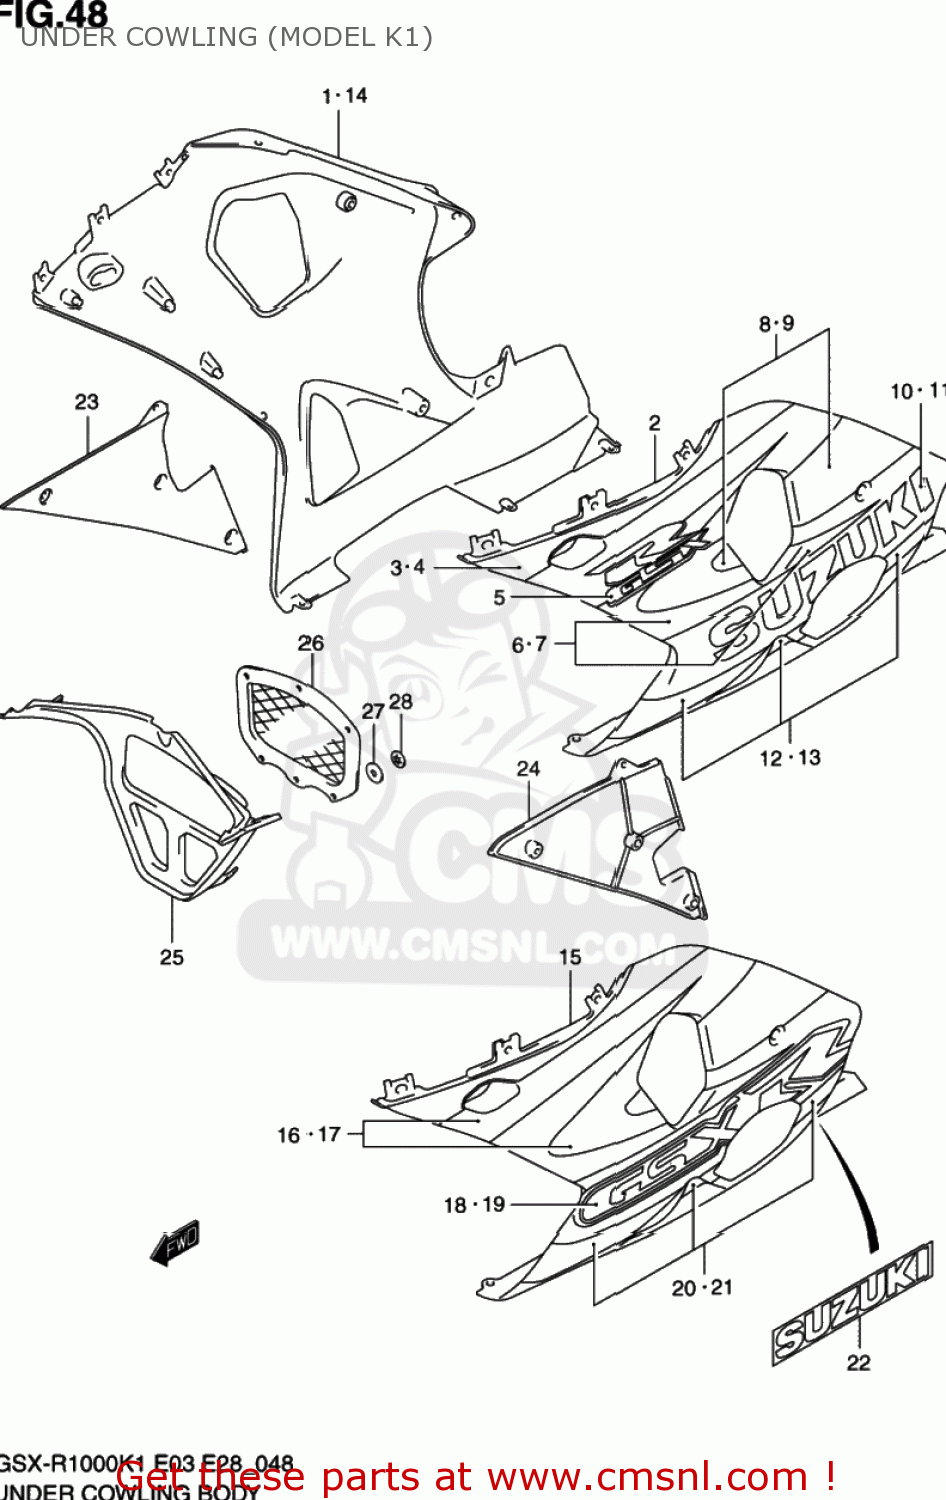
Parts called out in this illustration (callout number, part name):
1	COWLING ASSY,UNDER,R
2	COWLING ASSY,UNDER,L
3	TAPE,COWL UNDER UPR,R
4	TAPE,COWL UNDER UPR,L
5	EMBLEM,COWLING UNDER,GSX
6	TAPE SET,COWL UNDER,R
7	TAPE SET,COWL UNDER,L
8	TAPE,COWL UNDER MIDDLE,R
9	TAPE,COWL UNDER MIDDLE,L
10	EMBLEM,UNDER,SUZUKI,R
11	EMBLEM,UNDER,SUZUKI,L
12	TAPE SET,COWL UNDER LWR,R
13	TAPE SET,COWL UNDER LWR,L
14	COWLING ASSY,UNDER,R
15	COWLING ASSY,UNDER,L
16	TAPE SET,COWL UNDER UPR,R
17	TAPE SET,COWL UNDER UPR,L
18	EMBLEM,COWLING UNDER,GSXR,R
19	EMBLEM,COWLING UNDER,GSXR,L
20	TAPE,COWL UNDER LWR,R
21	TAPE,COWL UNDER LWR,L
22	EMBLEM,COWLING UNDER,SUZUKI
23	COWLING,UNDER INNER,R
24	COWLING,UNDER INNER,L
25	COWLING,UNDER CTR
26	NET,UNDER COW CTR
27	CUSHION
28	NUT
